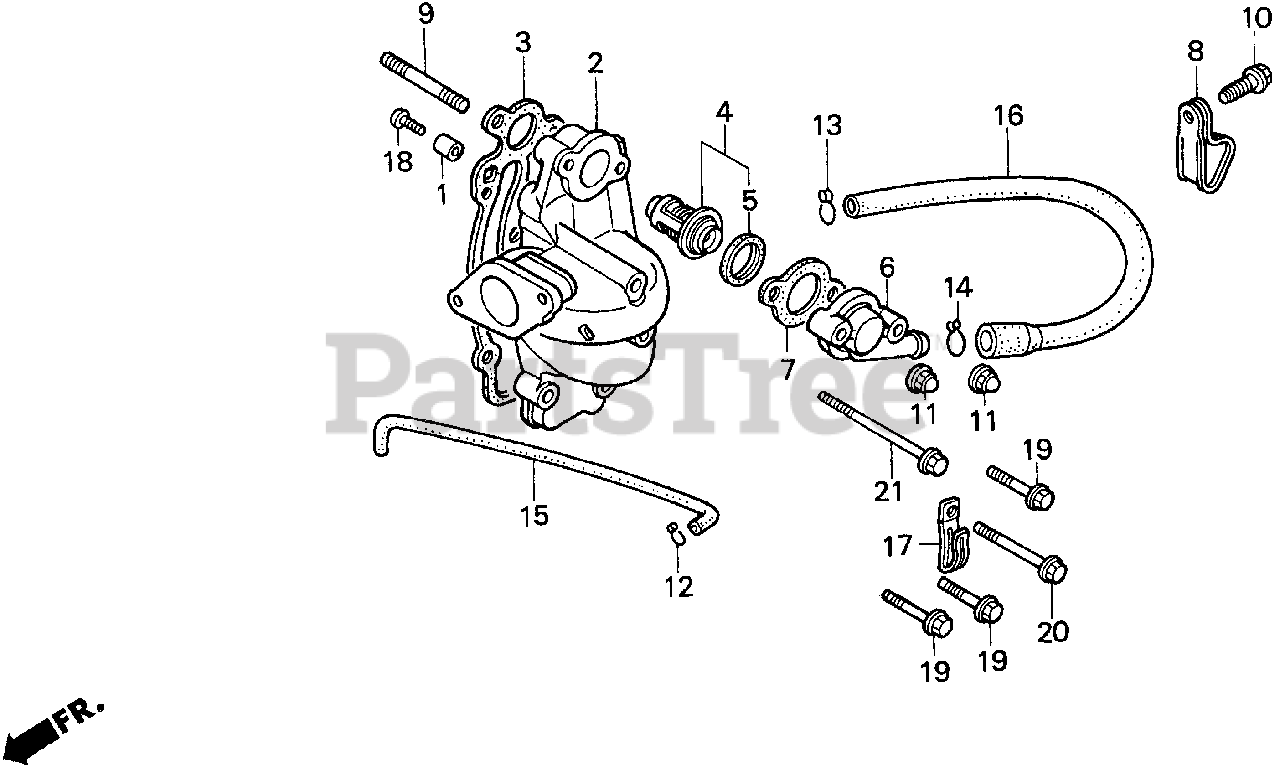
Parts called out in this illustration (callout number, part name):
1	METAL, ANODE
2	MANIFOLD, IN. *NH8* (DARK GRAY)
3	GASKET, IN. MANIFOLD
4	THERMOSTAT ASSY.
5	RUBBER, THERMOSTAT
6	COVER, THERMOSTAT *NH8* (DARK GRAY)
7	GASKET, THERMOSTAT COVER
8	CLAMP, TUBE
9	BOLT, STUD (6X52)
10	BOLT, FLANGE (6X12)
11	NUT, CAP (6MM)
12	CLIP, TUBE (B8)
13	CLIP, TUBE (B12.5)
14	CLIP, TUBE (B16)
15	TUBE, WATER CHECK
16	TUBE, WATER RETURN (A)
17	CLIP, TUBE
18	SCREW, PAN (5X20)
19	BOLT, FLANGE (6X30)
20	BOLT, FLANGE (6X60)
21	BOLT, FLANGE (6X75)
